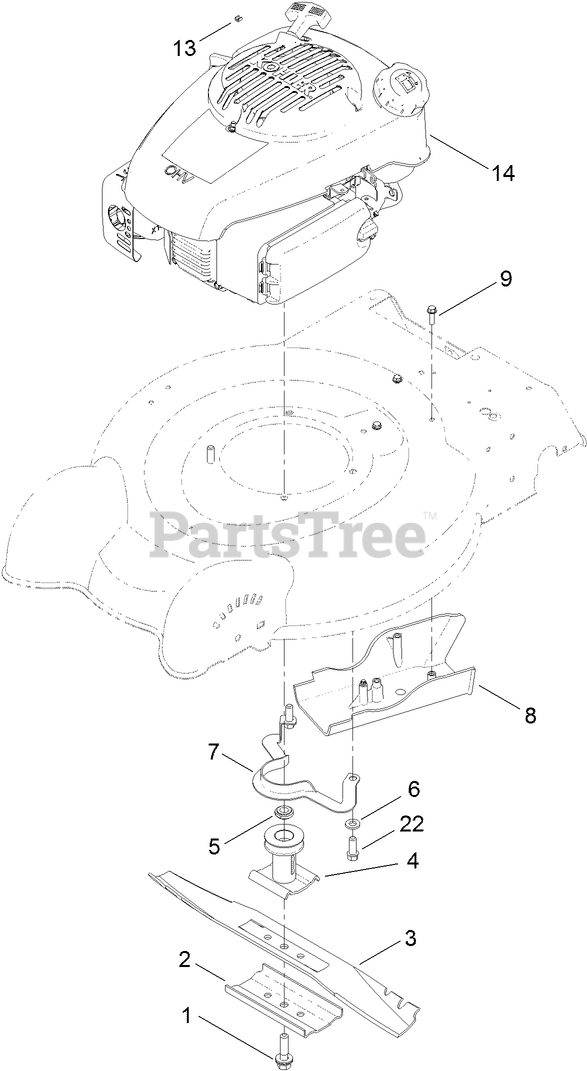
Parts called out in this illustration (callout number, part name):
2	SUPPORT-BLADE
4	DRIVER-BLADE
5	SPACER-DRIVER
6	SCREW-TAPTITE
8	COVER-BELT
9	SCREW-HWH
13	STOP-ROPE
22	WASHER-FLAT
